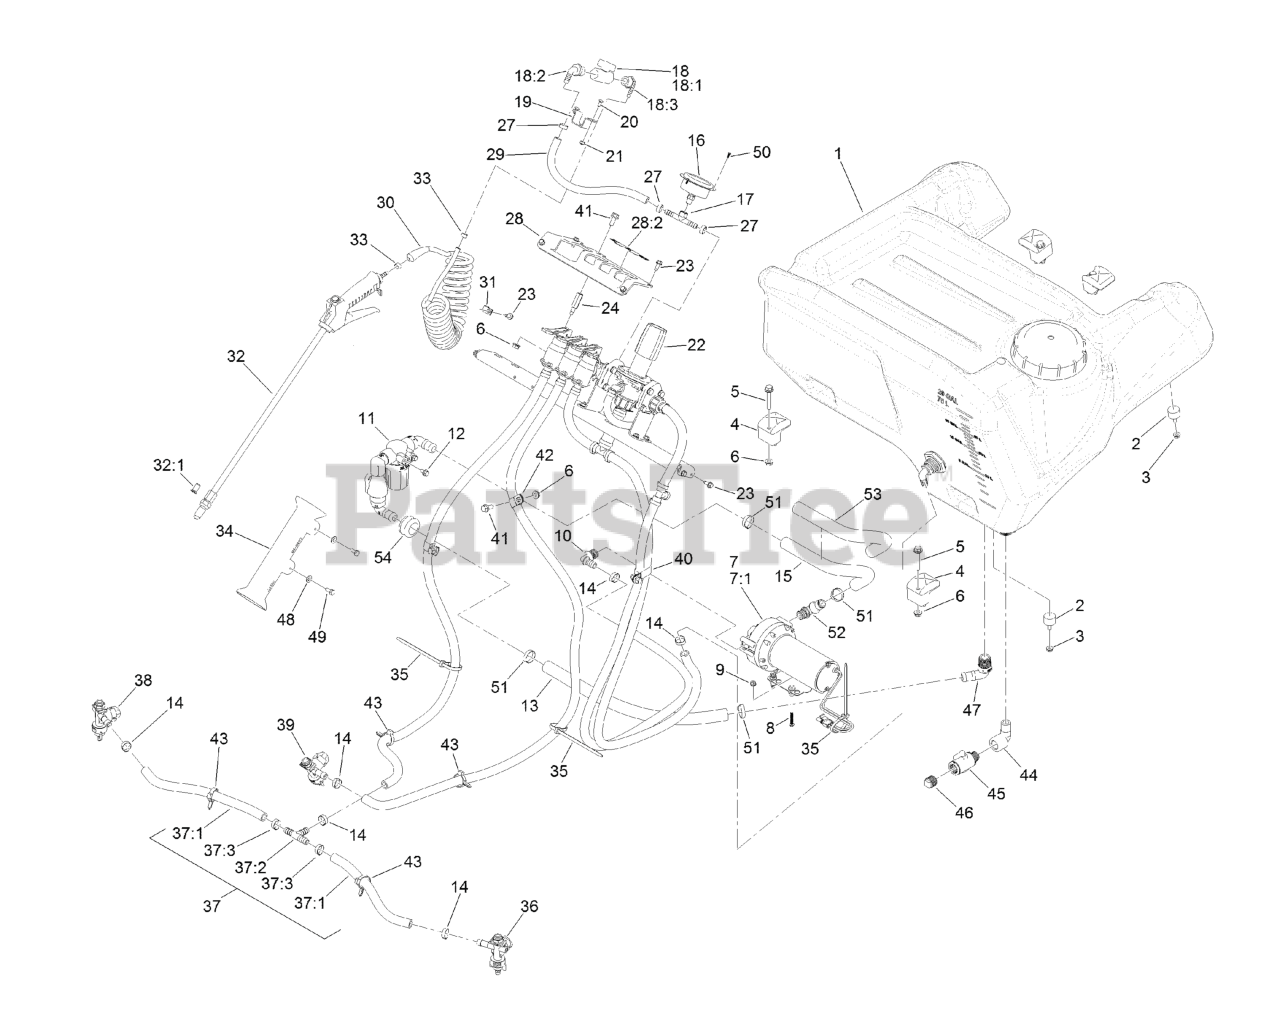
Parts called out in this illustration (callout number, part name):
1	TANK-SPRAYER
5	SCREW-HHF
7	PUMP-DIAPHRAGM, 3.8 GPM
7:1	KIT-DIAPHRAM PUMP
8	SCREW-SHWH
10	FITTING-ELBOW, BARBED
11	STRAINER ASM
12	SCREW-HHF
13	HOSE-WATER
15	HOSE-WATER
16	GAUGE-PRESSURE
17	FITTING-TEE
18	Wand Control ASM
18:1	VALVE-BALL
18:2	FITTING-ELBOW-90
18:3	FITTING-ELBOW-90
19	BRACKET-VALVE
20	BOLT-CARR
21	NUT-LOCK, NI
22	Control Valve Manifold ASM
23	SCREW-HWH
24	SPACER-MOUNT, MANIFOLD
28	COVER-CONTROLS
28:2	DECAL-CONTROL, LEVER
29	HOSE-WATER, 3/8 PVC RED
30	HOSE-COILED
31	CLAMP-R
32	SPRAY WAND ASM
32:1	STRAINER-NOZZLE, 50M 5PSI
34	HOLDER-WAND
35	TIE-PLASTIC
36	LEFT NOZZLE SUB ASM
37	HOSE ASM
37:1	HOSE-WATER
37:2	FITTING-TEE
38	RIGHT NOZZLE SUB ASM
39	CENTER NOZZLE SUB ASM
41	SCREW-HHF
42	CLIP-LOOM
43	CLAMP-HOSE
44	ELBOW-90 DEG
45	MICROVALVE
47	ELBOW-HOSEBARB
48	WASHER-FLAT
49	SCREW-HH
50	SCREW-TAP
52	FITTING-ELBOW
53	SLEEVE-CORRUGATED, SPLIT
54	GROMMET
